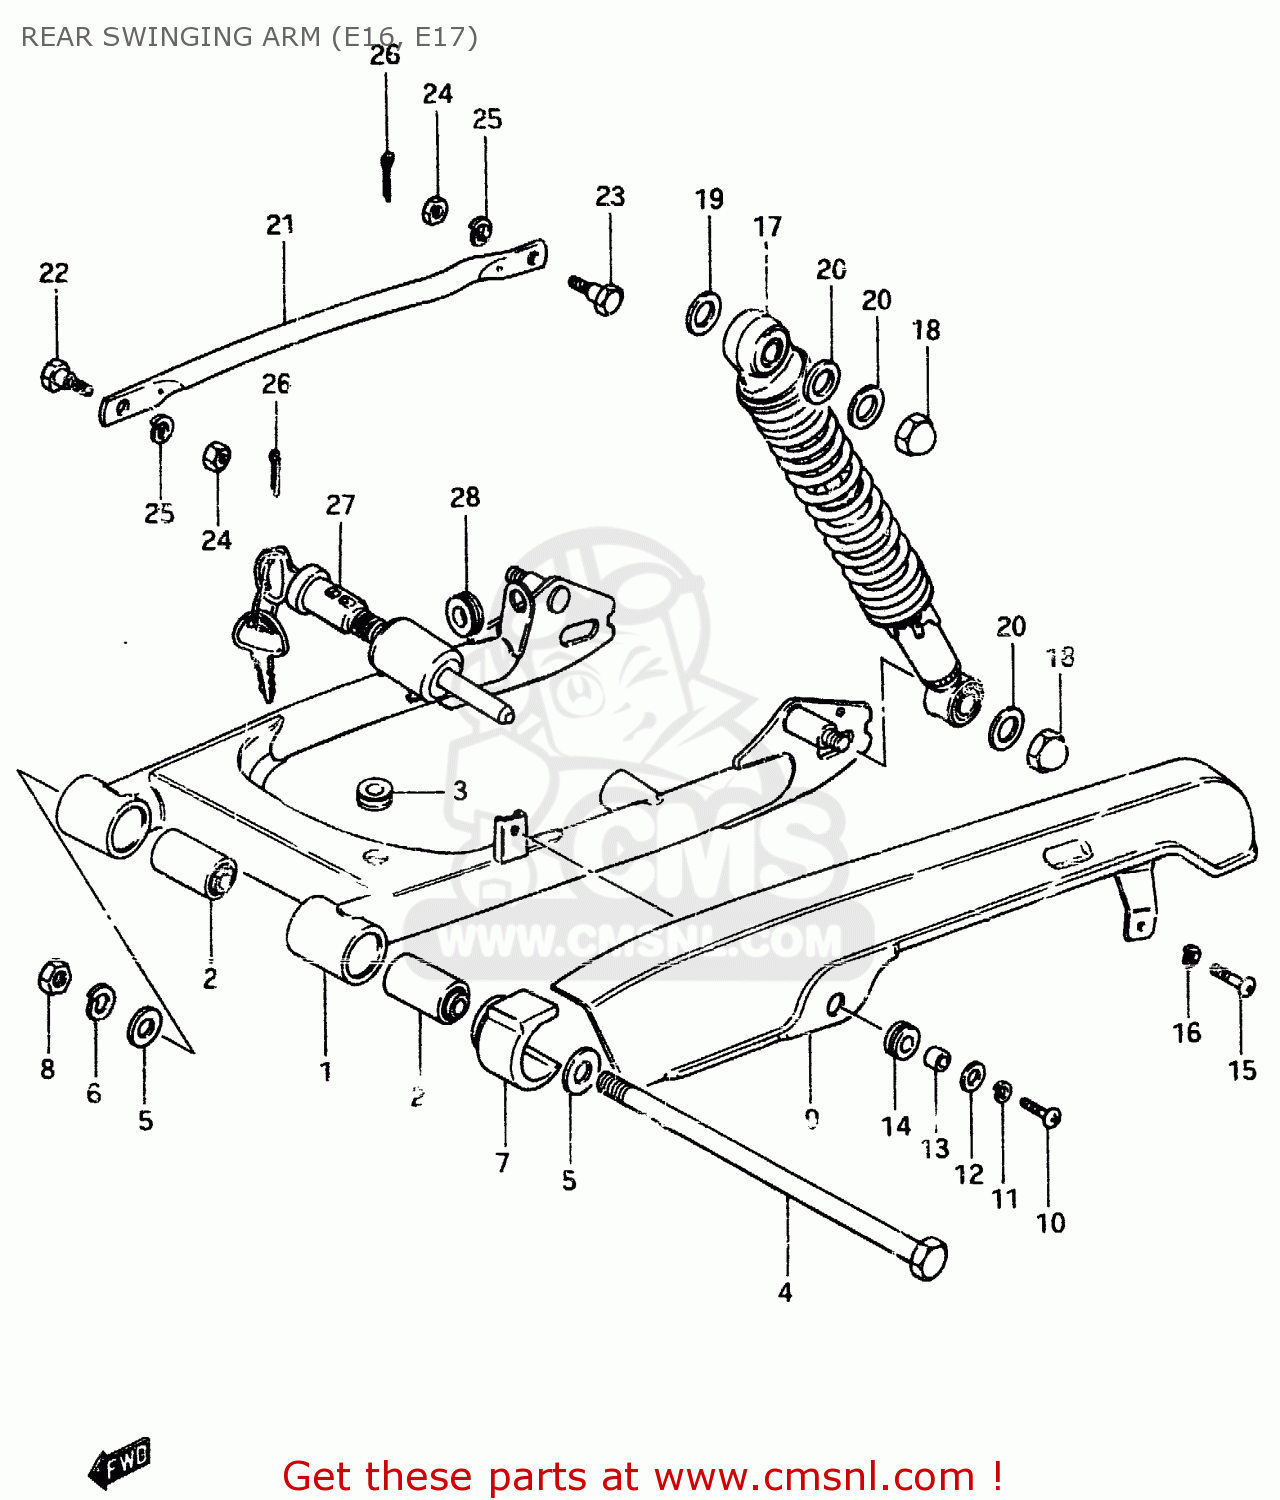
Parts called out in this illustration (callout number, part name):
1	SWINGING ARM SET, REAR
2	BUSH
3	CUSHION
4	SHAFT,RR SHOCK ABSORBER UPR
5	WASHER
6	LOCK WASHER
7	BUFFER,CHAIN TOUCH DEFENSE
8	NUT
9	CHAIN CASE
10	SCREW
11	LOCK WASHER
12	WASHER (6.5X20X1.2)
13	SPACER (7X9X7)
14	CUSHION
15	SCREW 6X12
16	LOCK WASHER
17	SHOCK ABSORBER, REAR
18	NUT, LOWER LH
19	WASHER
20	WASHER
21	TORQUE LINK, REAR
22	BOLT(8X22)
23	BOLT(8X26.5)
24	NUT
25	LOCK WASHER
26	PIN 20X20
27	LOCK SET, WHEEL
28	CUSHION
